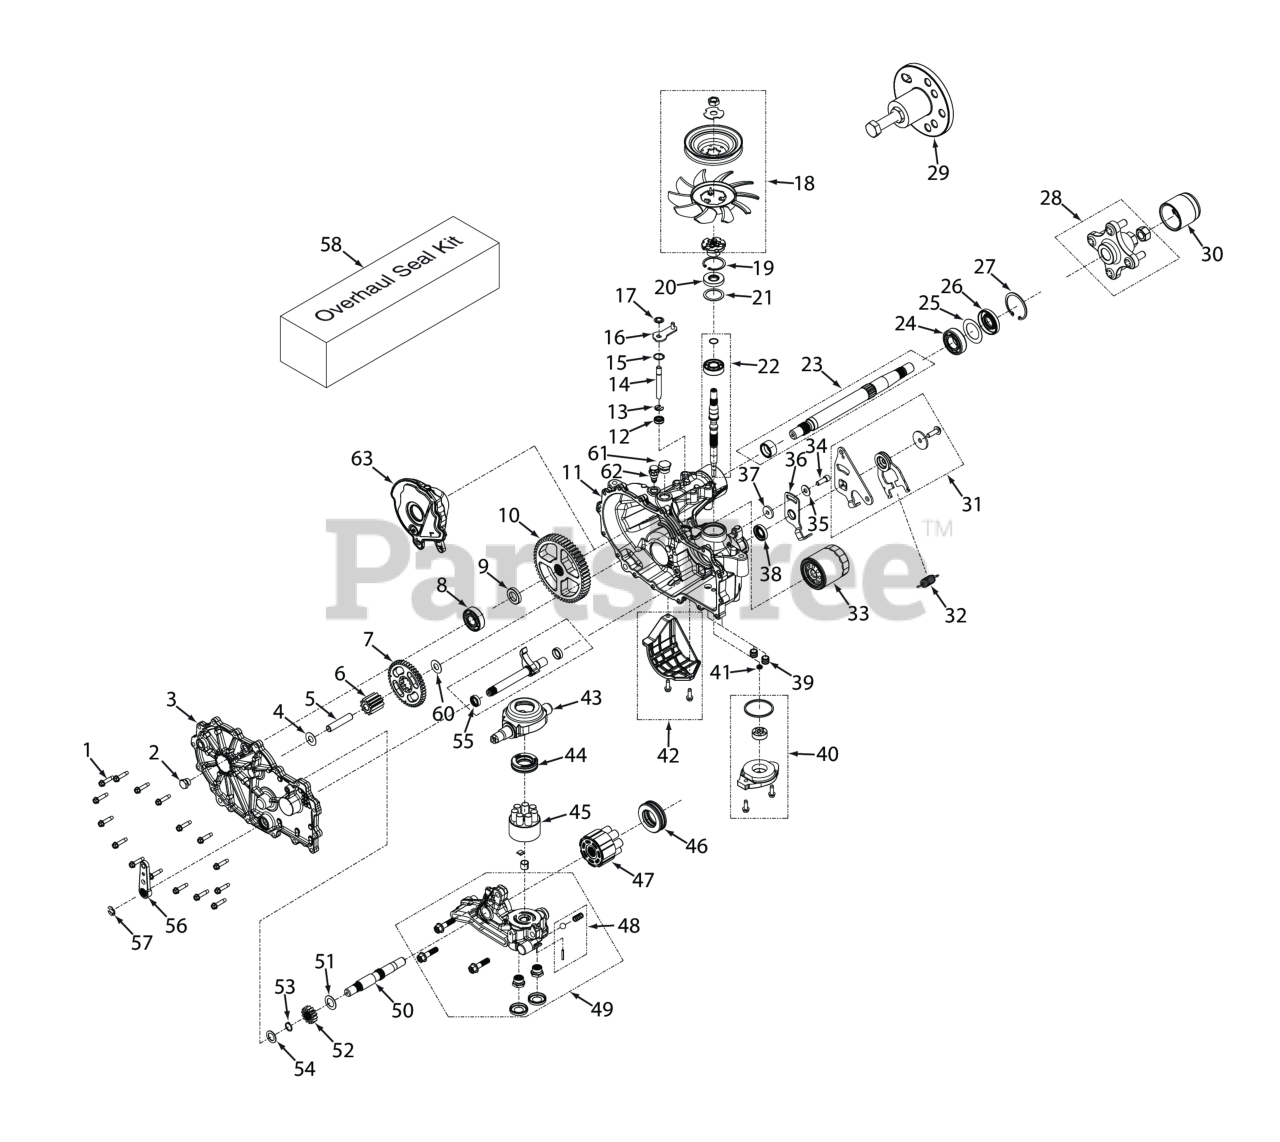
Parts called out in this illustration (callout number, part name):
1	Bolt, Hex Head 1/4-20 x 1-1/8"
2	Plug, External Hex Vent 9/16-18
3	Kit, Side Cover LH
4	Washer, .5 x 1.0 x .03
5	Jackshaft Pin
6	Gear, 11T
7	Gear, 45T
8	Kit, Bearing
9	Spacer, .750 x 1.320 x .257
10	Gear, 54T
11	Kit, Main Housing LH, Charge, Control
12	Seal, Lip, .375 x .75 x .25
13	Ring, .Retaining .375 External
14	Rod, By-Pass
15	R i n g , Retaining .750 Internal
16	Arm, Bypass (LH)
17	Ring, Retainging .375 External
18	Kit, Fan/Pulley
19	R i n g , Retaining 2.06 Internal
20	Seal, Lip 17 x 40 x 7
21	Washer, 1.23 x 1.56 x .04
22	Kit, Input Shaft
23	Kit, Shaft, Axle
24	Bearing, Ball 1.0 x 52 x 15 Open
25	Spacer, 1.355 x 2.035 x .021
26	Seal, Lip TC4 1.0 x 2.06 x .38
27	R i n g , Retaining 2.06 Internal
28	Hub Kit
29	Kit, Hub Puller
30	Cap, Axle
31	Kit, RTN Bi-Directional (Right Side)
32	Spring, Extension, RTN - 44lbs
33	Filter, Oil
34	Bolt, Hex Head Cap Screw 5/16-24 x 1" Patch
35	Washer, 7/16 x 7/8 OD x .06 HT
36	Arm, Neutral (Left Side)
37	Spacer, .32 ID x 1.005 OD x .1495 Thk
38	Seal, Lip 18 x 32 x 7
39	Tube, Charge Triple O-ring
40	Kit, Charge Pump
41	Kit, Gerotor Seal
42	Kit, Filter Guard (LH)
43	Trunnion, Swashplate
44	Ball Thrust Bearing
45	Kit, Cylinder Block
46	Thrust Ball Bearing Assembly
47	Kit, 16cc Cylinder Block Assembly (steam
48	Kit, Charge Relief
49	Kit, Charge Relief
50	Shaft, Motor
51	Washer, .72 x 1.16 x .04
52	Washer, Flat, .71 x 1.16 x .04
53	Ring, Retaining .625
54	Washer, HT .62 ID x 1.0 OD x .05 Thick
55	Kit, Inboard, RH Rot B / LH Rot A (LH)
56	Handle, Brake
57	Ring, Retaining External .375"
58	Kit, Seal (ZT-2800)
60	Washer, .5 x 1.0 x .03
61	Plug, 3/4-16
62	Fitting 9 /16 - 18, Breather
63	Expansion Tank, Internal LH
